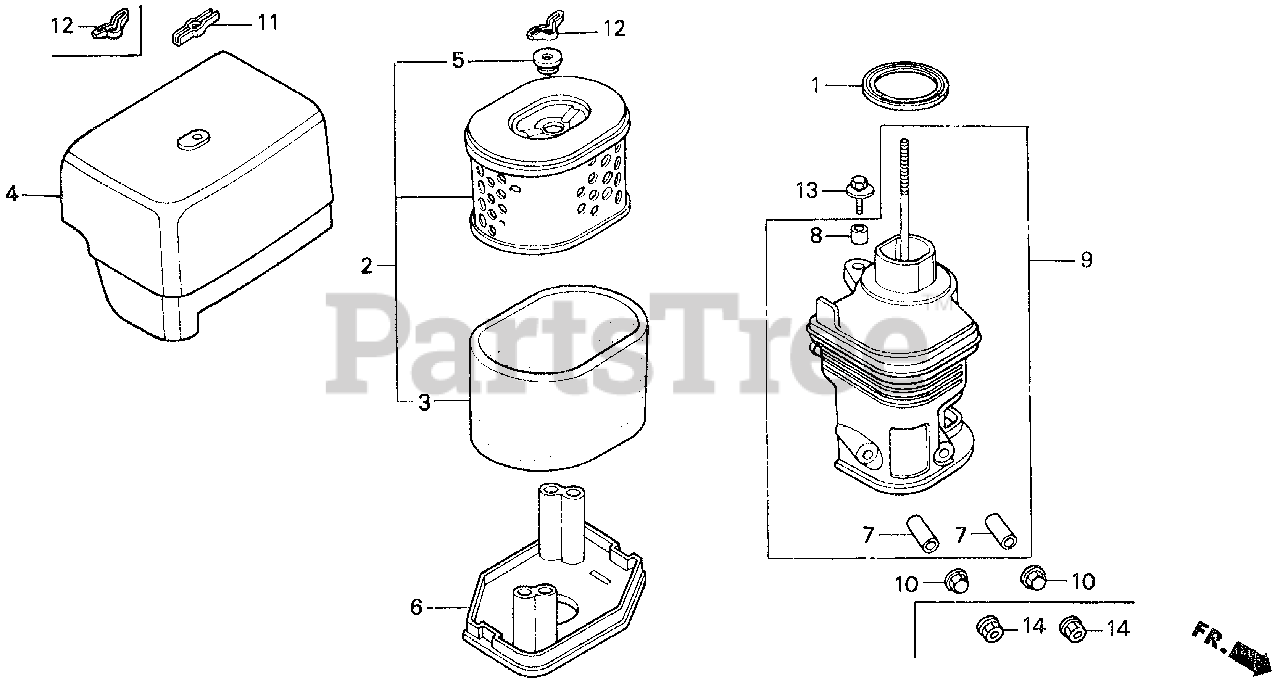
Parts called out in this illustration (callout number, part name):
1	GASKET, ELBOW
2	ELEMENT, AIR CLEANER
3	FILTER (OUTER)
4	COVER, AIR CLEANER
5	GROMMET, AIR CLEANER
6	NOSE, MUFFLER
7	COLLAR, AIR CLEANER
8	COLLAR B, AIR CLEANER
9	ELBOW, AIR CLEANER
11	WINGNUT (6MM)
12	WINGNUT, TOOL BOX SETTING
13	BOLT-WASHER (6X20)
14	NUT, FLANGE (6MM)
